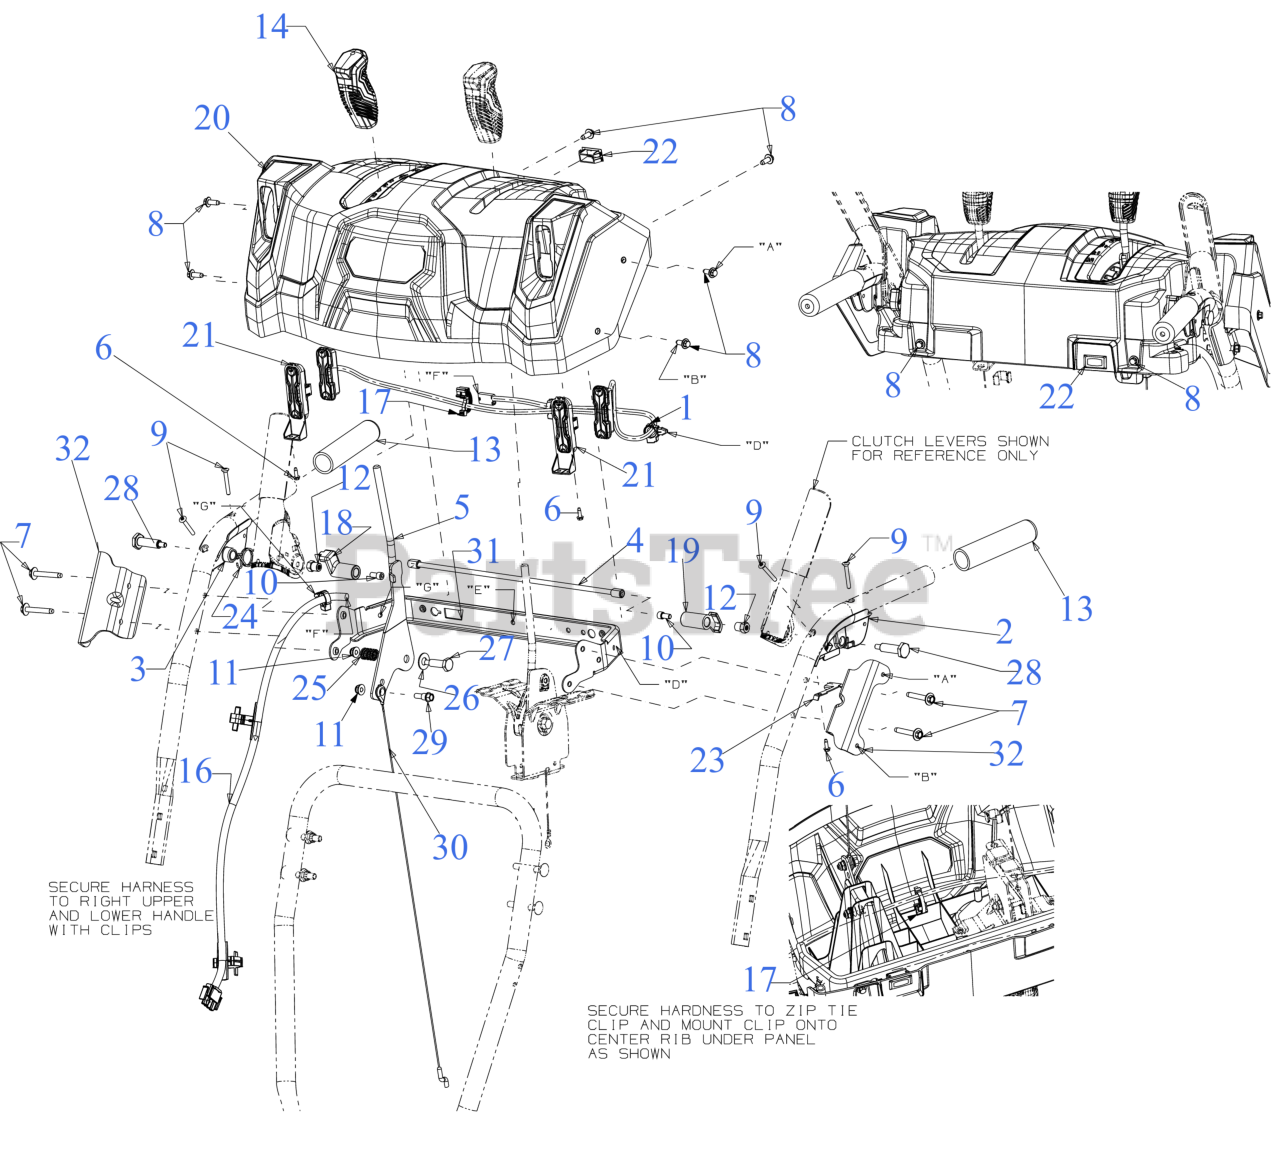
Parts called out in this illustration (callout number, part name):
1	HEADLIGHT HARNESS (W/LED)
2	CLUTCH LOCK HANDLE ASSEMBLY (LH)
3	CLUTCH LOCK HANDLE ASSEMBLY (RH)
4	PIVOT ROD
6	SCREW #8-16 x .50
7	SCREW 1/4-20 x 1.625
8	SCREW M6-1 x .625
9	SCREW #10-24 x 1.375
10	SCREW 1/4-20 x .50
11	FLANGE LOCK NUT
12	HEX NUT W/PATCH
16	LED HEADLIGHT HARNESS
17	EDGE MOUNT ZIP TIE CLIP
18	LOCK PLATE
19	CLUTCH LOCK CAM
20	HANDLE PANEL
21	LENS BEZEL
22	SWITCH PLUG
23	CLUTCH SPRING
24	TORSION SPRING
25	COMPRESSION SPRING
26	FLAT WASHER
27	SHOULDER SCREW
28	SHOULDER SCREW .437 x 1.345 1/4-20
29	SHOULDER SCREW .342X.335X1/4-20
30	SELECTION CABLE
